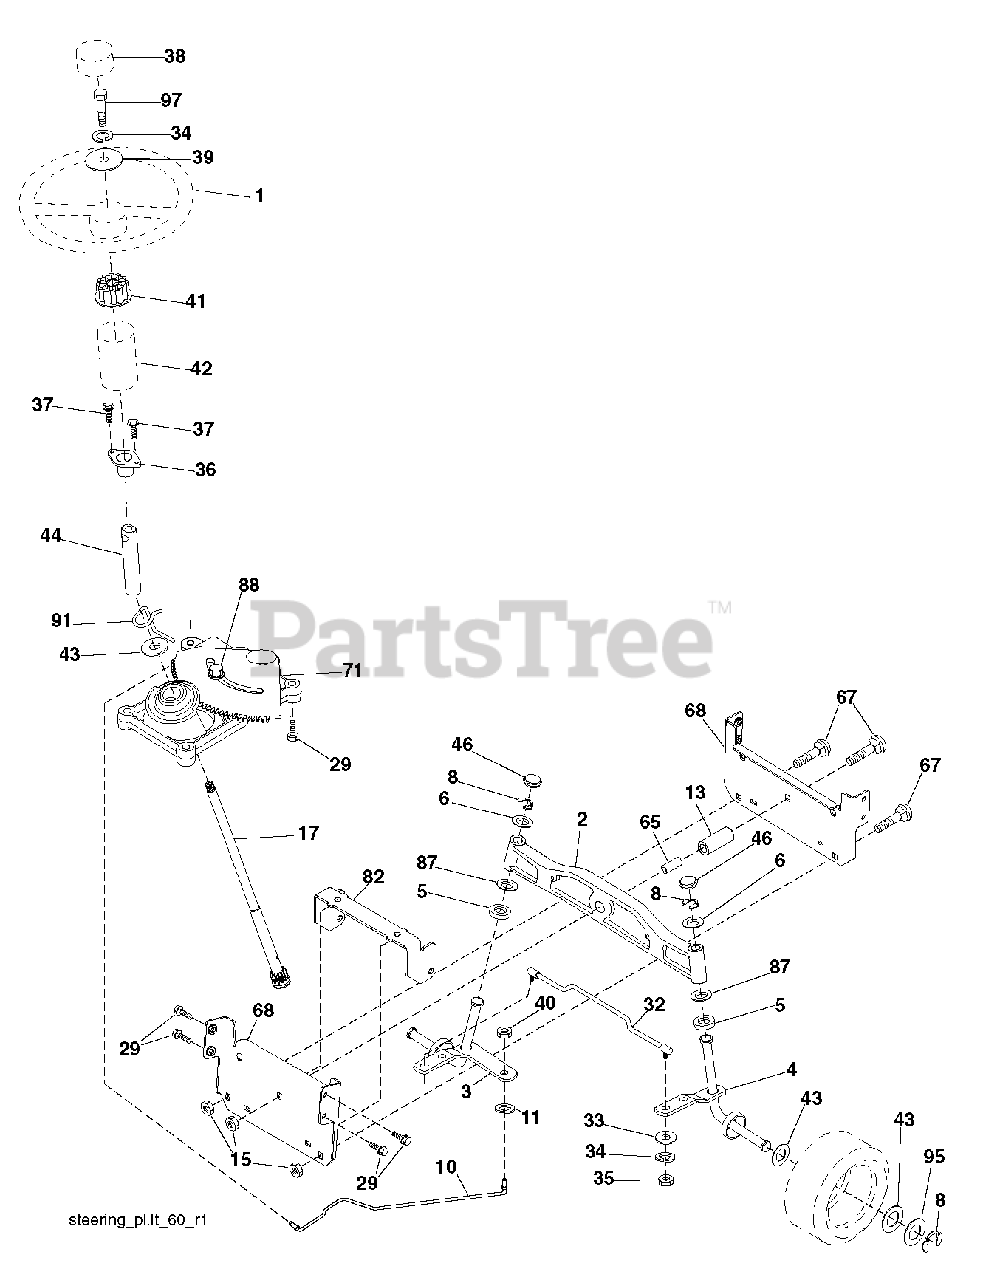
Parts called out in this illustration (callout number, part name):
1	WHEEL.STEERING.STDSRR.BLK/OV
2	AXLE ASSY FRONT
3	SPINDLE.ASM.LH.15"TIRES
4	SPINDLE.ASM.RH.15"TIRES
10	DRAGLINK.15".TIRES.2001
11	WASHER, LOCK 3/8
13	TUBE, PIVOT AXLE
15	NUT LOCK FLG 3/8-16 UNC
17	SHAFT STEERING SPLINE
29	SCREW, 3/8-16X3/4
32	ROD.ASM.TIE.BALL.JOINT.NOVAN
33	WASHER M
35	NUT, CROWNLOCK
36	BUSHING, STEERING
38	INSERT, WHEEL STEERING
40	NUT CROWNLOCK 3/8-24
41	ADAPTER, WHEEL STNG..
42	BOOT.STEERING.SHAFT.BLACK
44	SHAFT.EXTEN.STRG.SPLINE
65	SPACER.BRACE.AXLE
67	BOLT CARRIAGE
68	BRACE.AXLE.15"TIRES
82	BRACKET.SUSP.CHASSIS.FRONT.15
87	WASHER, FLAT .781 X 1 1/2"
88	BOLT, SHOULDER 7/16-20
91	CLIP.STEERING
95	WASHER.HARDENED
97	BOLT 5/16-18 X 4 W/PATCH
